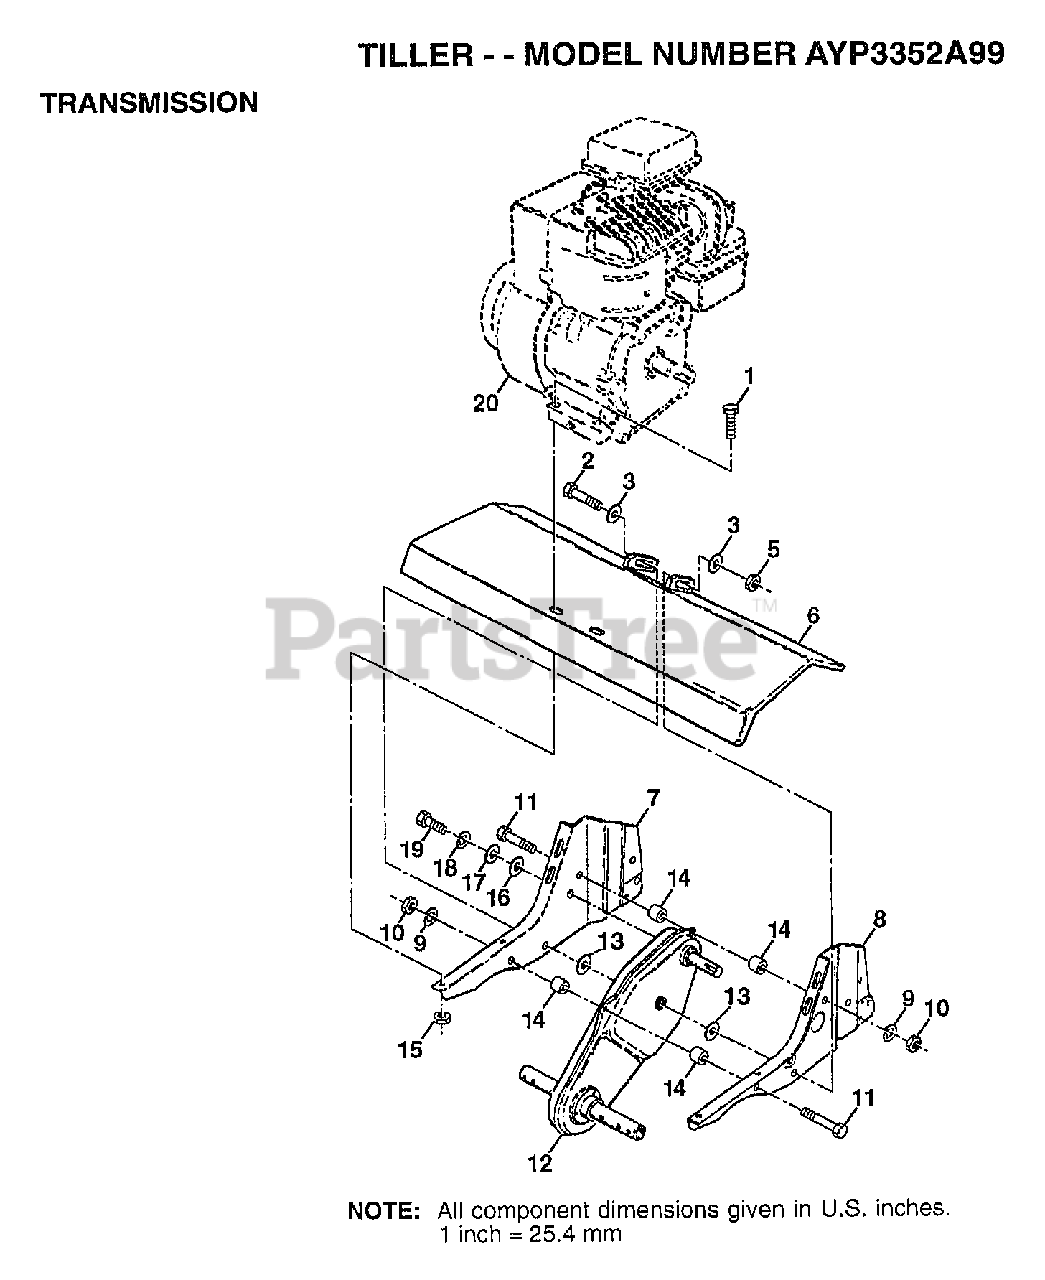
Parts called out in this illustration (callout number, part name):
1	BOLT.HEX.5/16-1.5
2	BOLT HEX 3/8-16
3	WASHER
5	NUT
6	"SHIELD, TINE"
7	BRACKET.ENGINE.RH
8	BRKT.ENGINE.LH
9	LOCKWASHER
10	NUT.HEX.5/16-18
14	SPLIT SPACER RT
16	WASHER
17	WASHER
18	LOCKWASHER
19	BOLT
